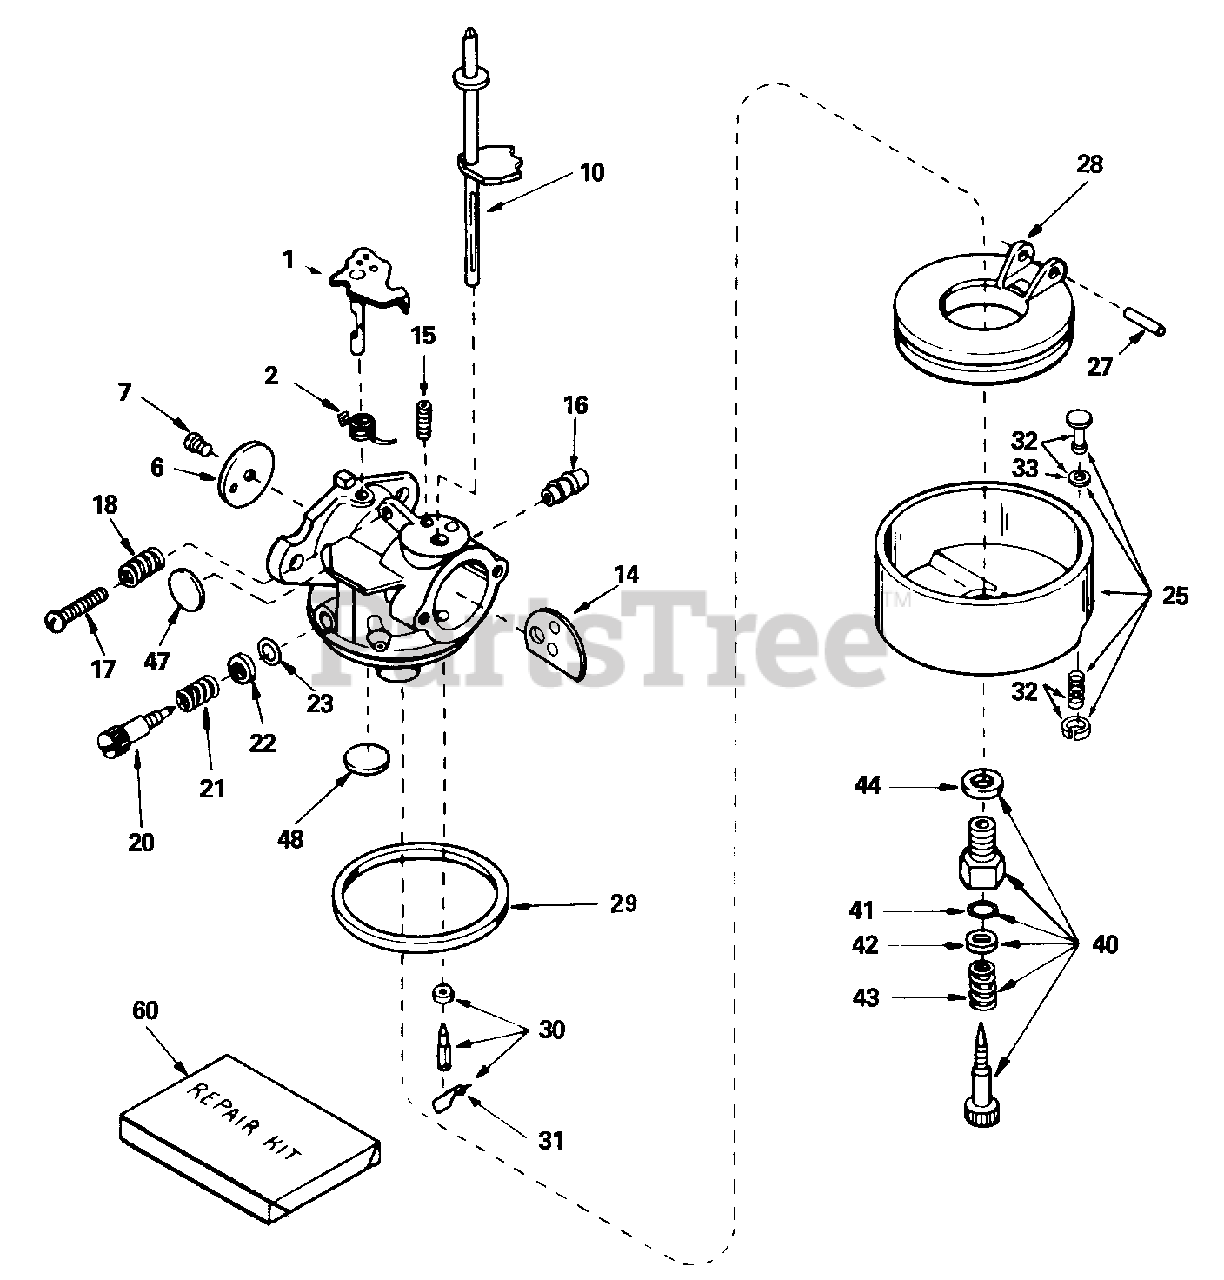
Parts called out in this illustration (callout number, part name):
1	Throttle Shaft & Lever Assy
2	Throttle Return Spring
6	Throttle Shutter
7	Shutter Screw
10	Choke Shaft
14	Choke Shutter
15	Choke Positioning Spring
16	Fuel Fitting
17	Throttle Crack Screw/Idle Speed Screw
18	Tension Spring
20	Idle Mixture Screw
21	Tension Spring
22	Idle Mixture Screw Washer
23	Idle Mixture Screw "O" Ring
25	Float Bowl Assy
27	Float Shaft
28	Float
29	Float Bowl "O" Ring
30	Inlet Needle, Seat & Clip
31	Spring Clip
32	Bowl Drain Assy
33	Drain Plunger Gasket
40	Main Adj. Screw Assy
41	High Speed Mixture Screw "O" Ring
42	High Speed Mixture Screw Washer
43	High Speed Mixture Screw Tension Spring
44	Bowl Nut Washer
47	Welch Plug, Idle Mixture Well
48	Welch Plug, Atmospheric Vent
60	Repair Kit
